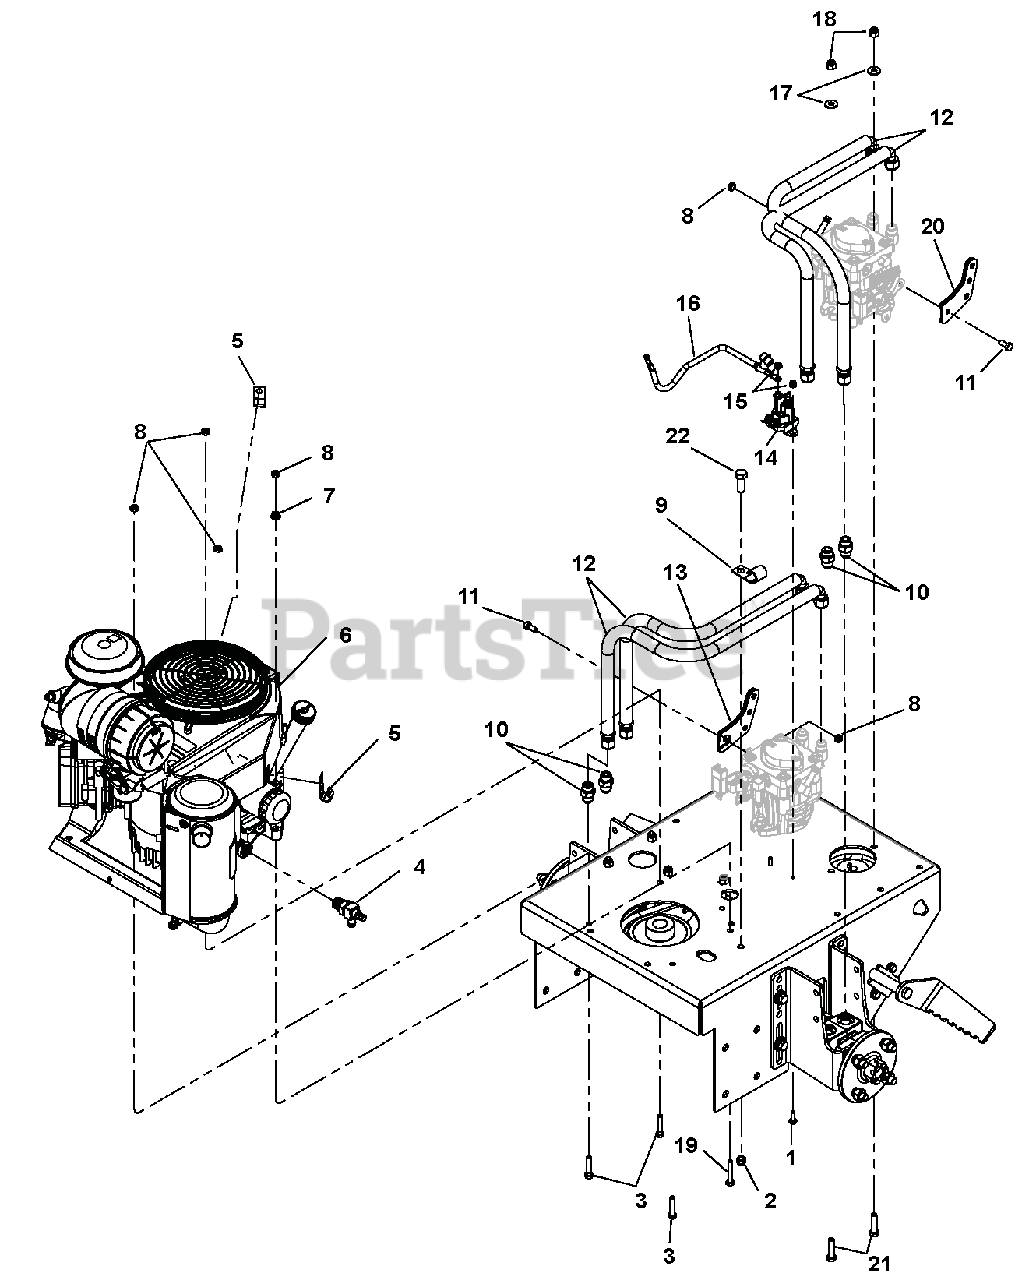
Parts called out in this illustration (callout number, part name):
1	BLT-HEX .25-20X.75 GR5 YWZC
2	LOCKNUT, 3/8-16 NYLOC Y
3	BLT-HEX .31-18X1.50 GR5 YWZC
4	FITTING, OIL DRAIN #
5	P-CLIP, .500 INSULATED
6	ENGINE, KAWASAKI 19HP FH580V
7	LOCKNUT, 5/16-18 WHIZ Y
8	LOCKNUT, 5/16-18 NYLOC Y
9	P-CLIP, .500 INSULATED
10	FITTING, STRAIGHT
11	BLT-HEX .31-18X.75 GR5 YWZC
12	HOSE, HYD 1/2 X 26 1/2 EZFLEX
13	WLDT, CSWS HYDRO PUMP ARM
14	SOLENOID
15	LOCKNUT, 1/4-20 NYLOC Y
16	CABLE, 12" STARTER
17	WASHER, .313 REG FLAT Y
18	LOCKNUT, 3/8-16 NYLOC Y
19	BLT-HEX .31-18X1.75 GR5 YWZC
20	WLDT, CSWS LH HYDRO PUMP ARM
21	BLT-HEX .38-16X1.50 GR5 YWZC
22	BLT-HEX .38-16X1.00 GR5 YWZC
